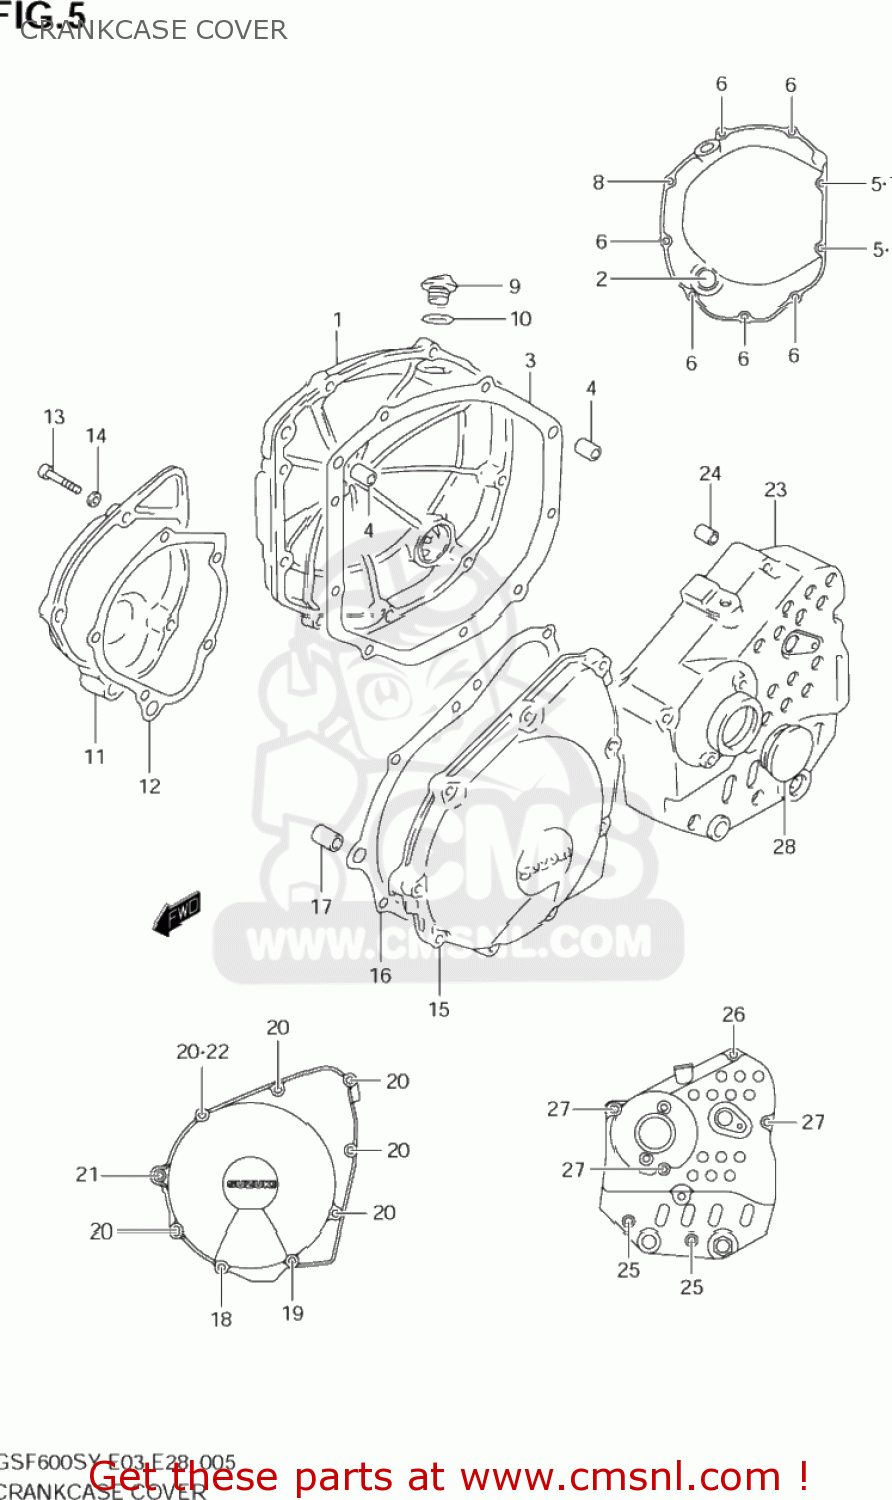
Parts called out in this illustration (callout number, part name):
1	COVER,CLUTCH
2	LENS,OIL LEVEL CHECK
3	GASKET,CL COVER (NAS)
4	PIN
5	GASKET(5.8X13X1.2) (NAS)
6	BOLT,CL.COVER
7	BOLT
8	BOLT
9	PLUG
10	O RING(D:3.1,ID:16.8)
11	COVER,SIGNAL GENERATOR
12	GASKET,SIGNAL GEN COVER (NAS)
13	BOLT(6X22)
14	GASKET(5.8X13X1.2) (NAS)
15	COVER,STARTER GEAR
16	GASKET,STARTER GEAR COVER (NAS)
17	PIN(8.4X11X20)
18	BOLT,OIL FILLE
19	BOLT,CRKCASE,R
20	BOLT,CL.COVER
21	BOLT
22	GASKET(5.8X13X1.2) (NAS)
23	COVER,ENGINE SPROCKET
24	PIN
25	BOLT
26	BOLT,CL.COVER
27	BOLT
28	CAP(OD:36)
